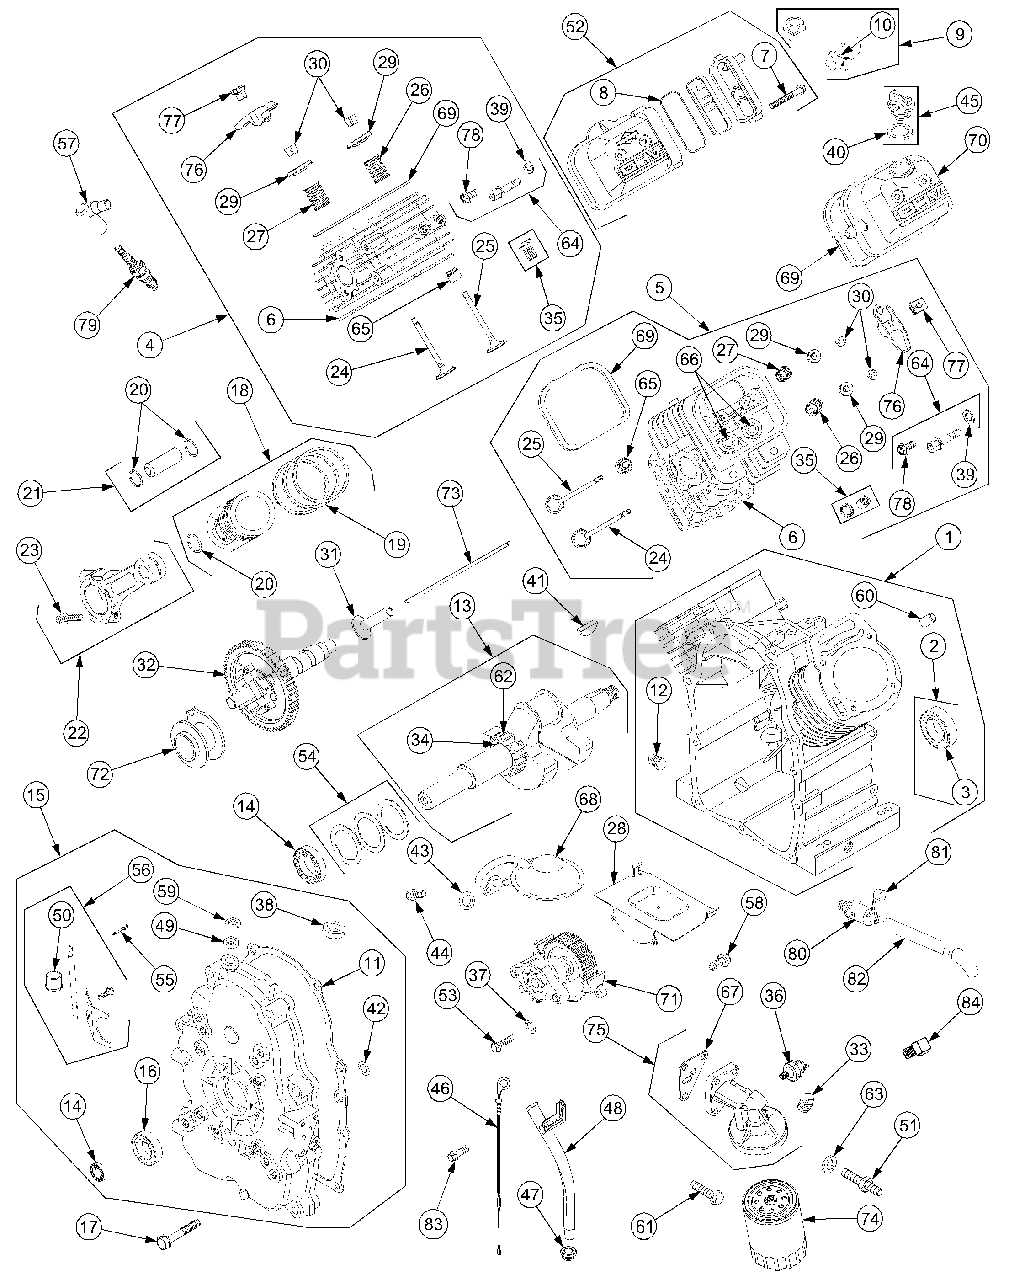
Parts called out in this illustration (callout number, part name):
1	Cylinder Assembly
2	Kit, Bushing/Seal (Magneto Side)
3	Seal, Oil
4	Head, Cylinder (#1)
5	Head, Cylinder (#2)
6	Gasket, Cylinder Head
8	Seal, O-ring
9	Tube, Breather
10	Clamp, Hose
11	Gasket, Crankcase
12	Plug, Oil Drain
13	Crankshaft
14	Bearing, Ball
15	Cover, Crankcase
16	Seal, Oil (PTO Side)
17	Screw (Crankcase Cover)
18	Piston Assembly
19	Ring Set
20	Lock, Piston Pin
21	Pin, Piston
22	Rod, Connecting
23	Screw, Connecting Rod
24	Valve, Exhaust
25	Valve, Intake
26	Spring, Valve (Intake)
27	Spring, Valve (Exhaust)
29	Retainer, Valve
30	Keeper, Valve
31	Tappet, Valve
33	Plug, Oil
34	Key, Timing
35	Adjuster, Rocker Arm
36	Switch, Oil Pressure
37	Seal, Oil Ring (Oil Pump)
38	Washer, Sealing
39	Washer, Sealing
40	Gasket, Oil Fill
41	Key, Woodruff
42	Seal, O-Ring
43	Seal, O-Ring
45	Plug, Oil Fill
47	Seal, Dipstick Tube
48	Tube, Dipstick
49	Bushing, Governor Shaft
50	Bushing, Governor Shaft
51	Stud, Oil Filter Adapter
52	Cover, Rocker Arm
54	Shim, End Play
55	Retainer, Governor Shaft
56	Shaft, Governor
57	Boot, Spark Plug
59	Seal, Governor Shaft
60	Pin, Locating
62	Gear, Timing
64	Stud, Rocker Arm
65	Seal, Valve
66	Bushing, Valve Guide
67	Gasket, Oil Adapter
68	Screen, Oil Pump
69	Gasket, Rocker Cover
70	Cover, Rocker Arm
72	Spool, Governor
73	Rod, Push (Steel)
74	Filter, Oil
75	Adapter, Oil Filter
76	Arm, Rocker
77	Pivot, Rocker Arm
78	Screw, Rocker Cover
79	Spark Plug
80	Drain, Oil
82	Hose, Oil Drain
83	Screw, Dipstick Tube
84	Connector, Filter Adapter
